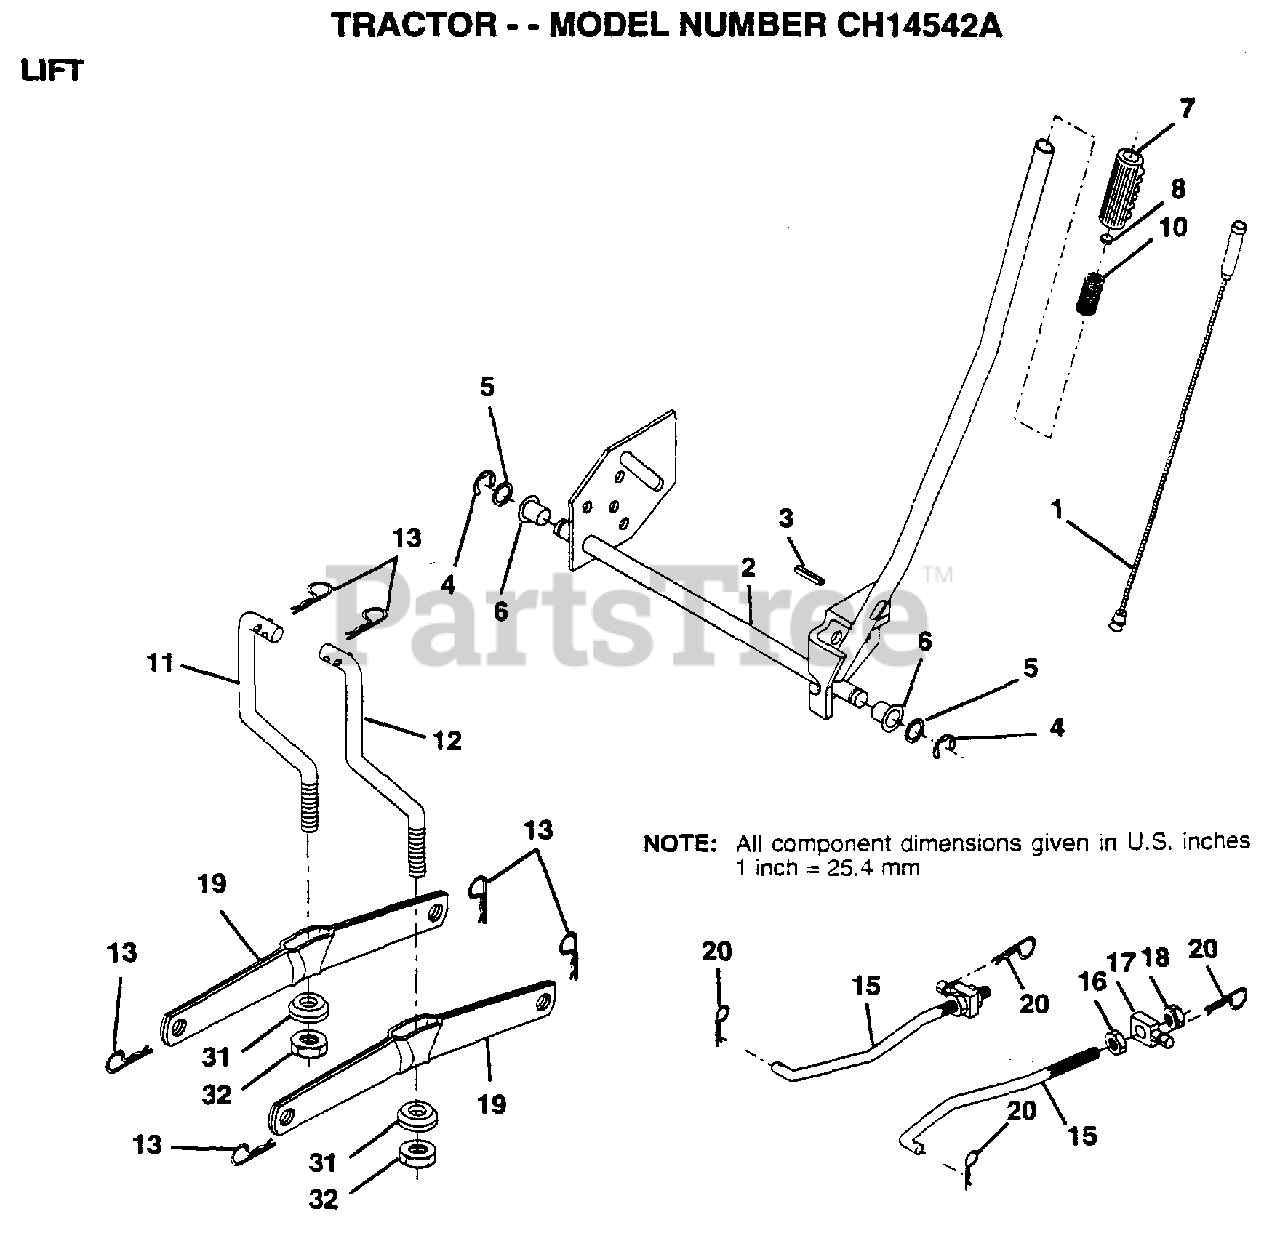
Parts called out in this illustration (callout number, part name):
1	WIRE ASM
3	PIN-GROOVE LT
5	WASHER
6	NYLON BEARING
7	GRIP
15	LINK.FRONT
16	NUT
17	TRUNION
18	NUT.LK.W/WSH.1/2.
19	ARM SUSP REAR
20	RETAINER.SPRING
31	BEARING PVT LH
32	NUT.CROWNLOCK.3/8
